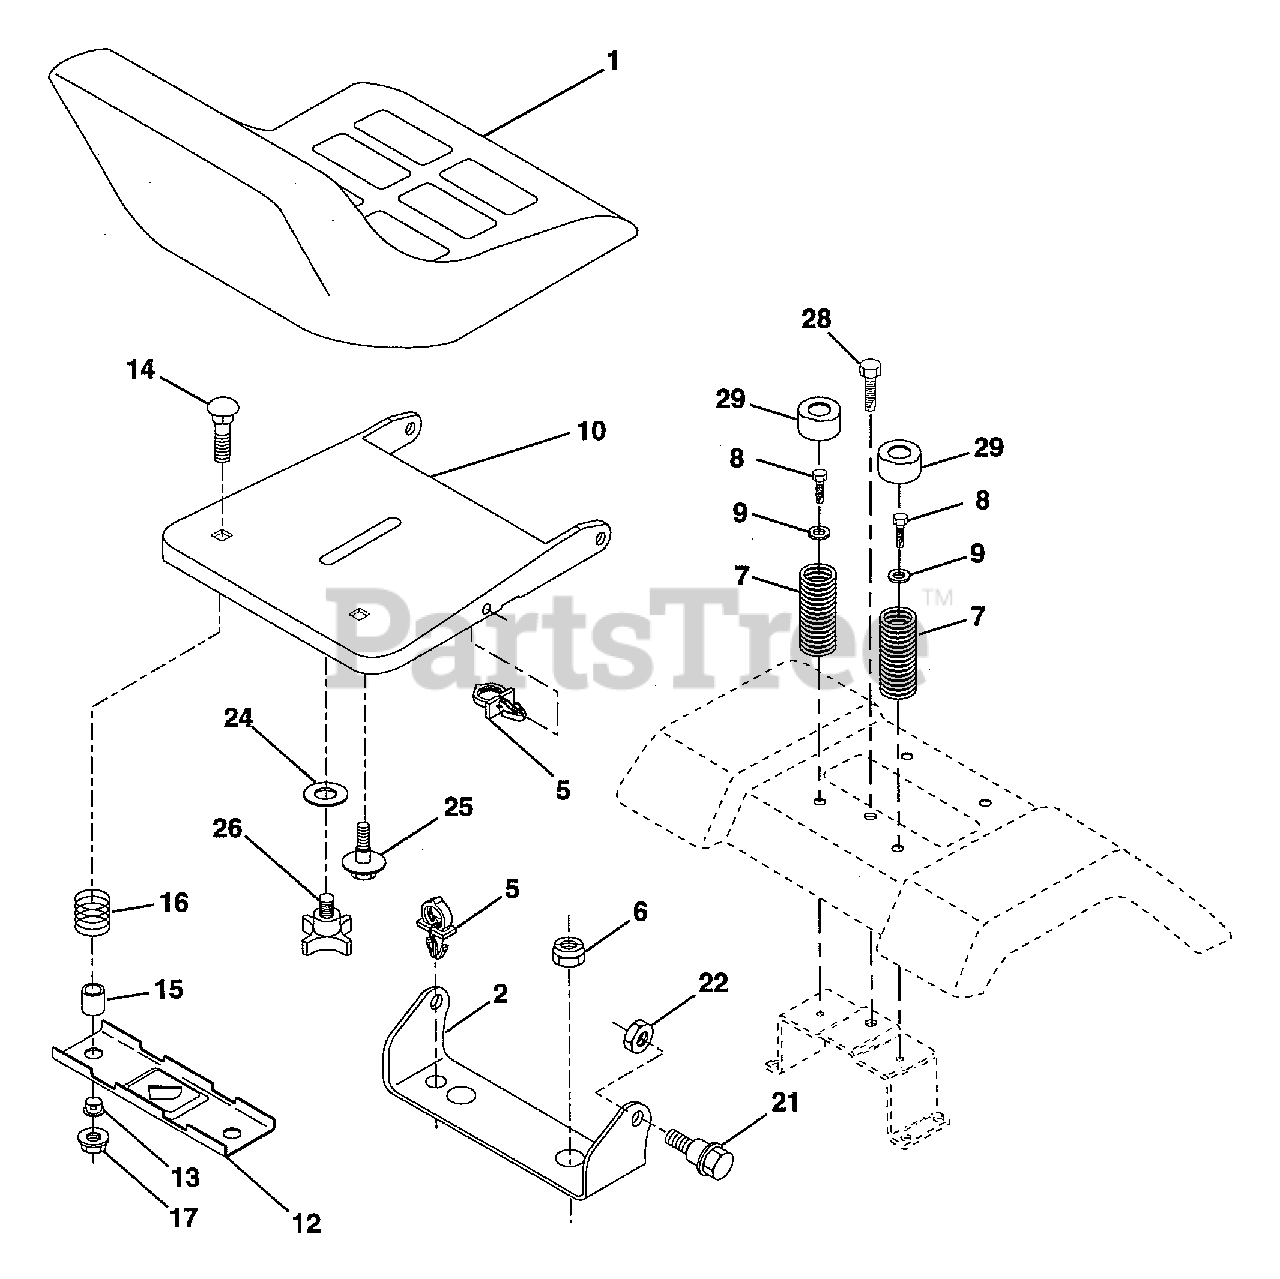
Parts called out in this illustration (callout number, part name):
1	Seat V-550 Gry/blk Std
2	Bracket Pivot Seat
5	Clip, Push-In
6	Nut Lock Hex w/Wsh 3/8-16 Unc
7	Spring Seat Cprsn 2 250 Blk Zi
8	Screw Hwsh Thdrol 5/16-18 x 1/2
9	Washer 13/32 X 1 X 14 Ga
10	Pan Seat
12	Bracket Mounting Switch
13	Bushing Snap Blk Nyl 50 Id
14	Bolt Rdhd Sht Nk 1/4-20x1-3/8
15	Spacer Split 28x 88 Yel Zinc
16	Spring Cprsn 1 310 BIk Pnt
17	Nut Lock 1/4 Lge FIg Gr 5 Zinc
21	Bolt Shoulder 5/16-18 Unc Blkz
22	Nut Crown Lock 5/16-18
24	Washer 17/32 X 1-3/16 X 12 Ga
25	Bolt Shoulder 5/16-18 X 62
26	Knob Seat 1/2-13unc Blk
28	Screw Thdrol 3/8-36 x 1/2
29	Cap Spring Seat
